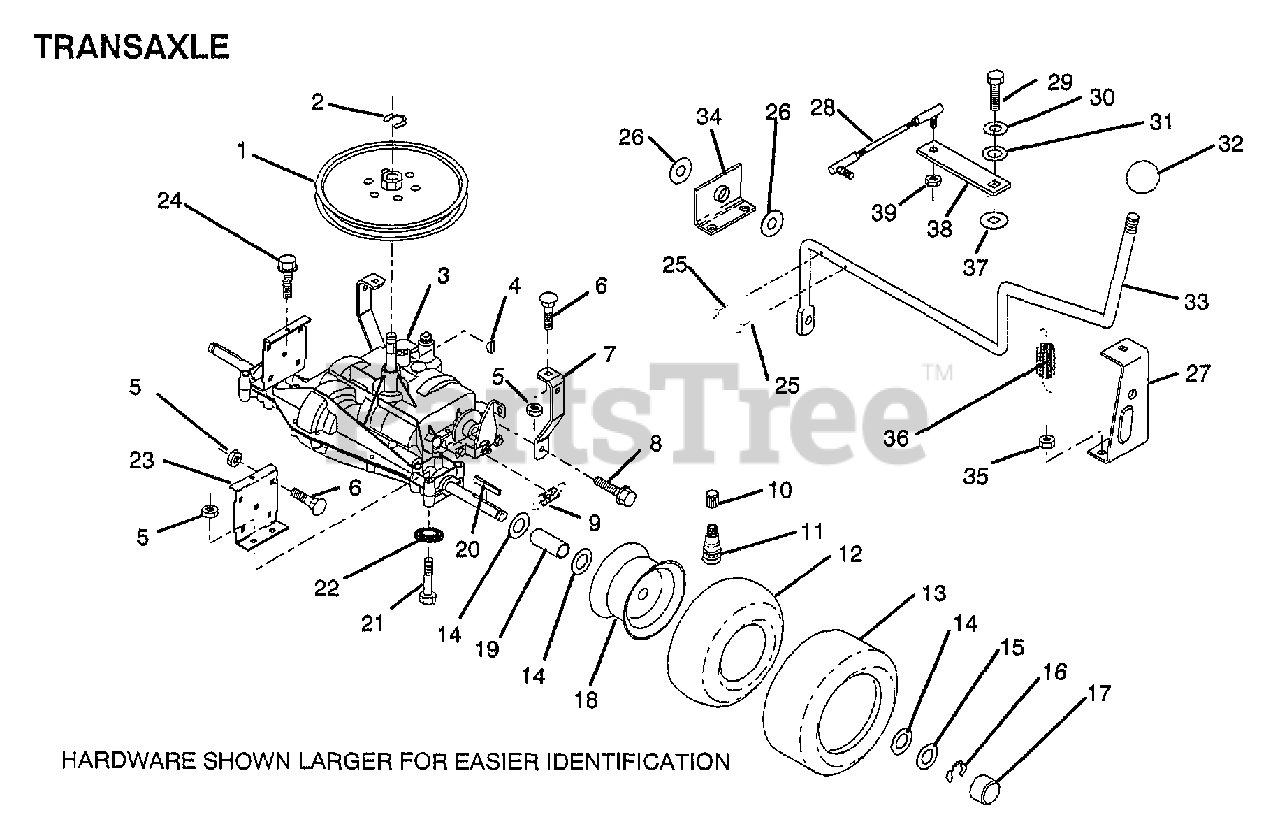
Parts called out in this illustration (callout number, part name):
1	PULLEY
3	TRANSAXLE PEERLESS 5 SPEED
6	BOLT
7	"STRAP,TORQUE"
8	SCREW LT
10	VALVE CAP
11	VALVE STEM LT
12	TUBE.16X6.5/7.5-8
14	WASHER
15	WASHER
16	E-RING LT
17	HUB CAP
19	SPACER
20	SQUARE KEY
21	BOLT
23	"BRKT,TRANSAXLE"
24	SCREW
25	PIN COTTER 1/8
28	LINK SHIFT
30	LOCKWASHER
31	WASHER LT
32	KNOB T (1/2-HOLE)
34	"SUPT,HDLE SHT LH"
36	EXT SPRING
37	WASH-SHFT PLT LT
39	NUT.LOCK.5/16-24
